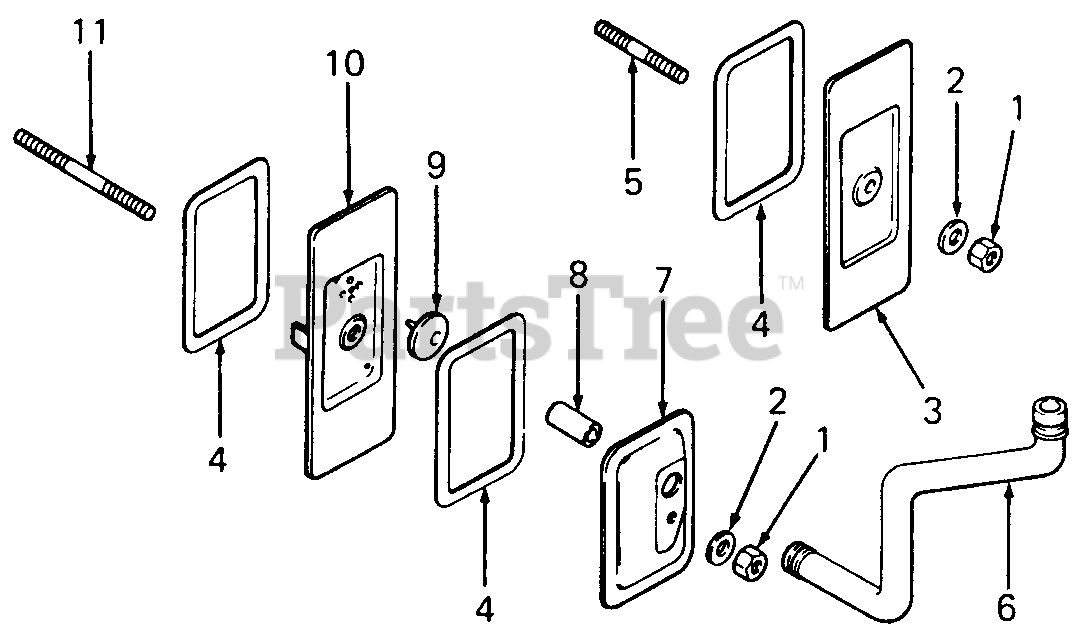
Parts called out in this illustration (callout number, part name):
1	Nut, Hex, 1/4-20
2	Washer, Plain, 1/4
3	Cover, #2 Cylinder Valve
4	Gasket, Valve Cover
5	Stud, #2 Cylinder Valve Cover, 1/4-20 X 2-1/4
6	Hose, Breather
7	Cover, #1 Upper Cylinder Valve
8	Seal, Breather
9	Valve, Umbrella
10	Cover, #1 Lower Cylinder Valve
11	Stud, #1 Cylinder Valve Cover, 1/4-20 X 3-1/4
